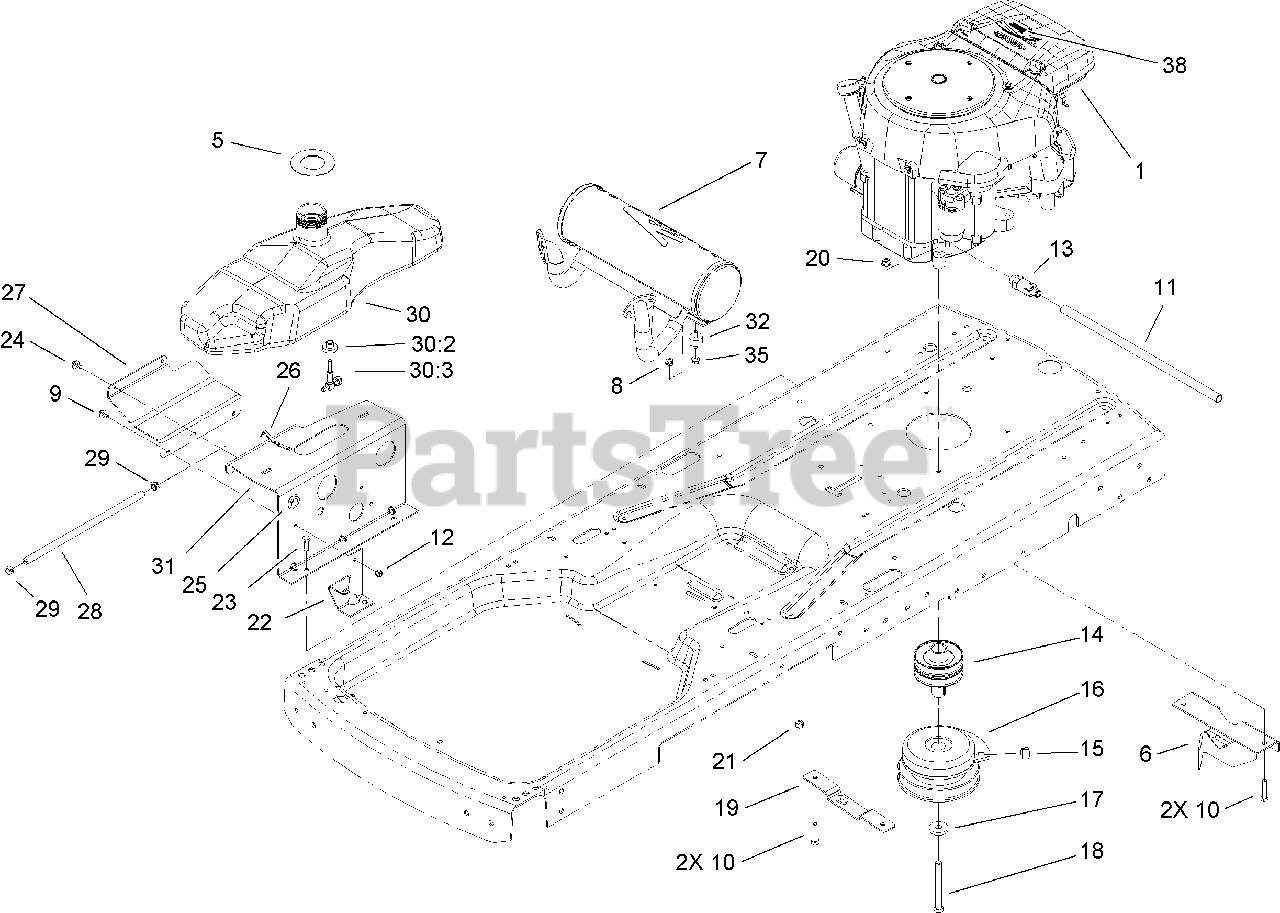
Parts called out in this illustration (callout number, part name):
5	SEAL-FOAM
6	BRACKET-PIVOT
9	SCREW-HWH
10	SCREW-HH
11	TUBE-DRAIN, OIL
12	NUT-LOCK, NI
13	VALVE-DRAIN, OIL
14	PULLEY-ENGINE
16	CLUTCH-PTO, ELECTRIC
18	SCREW-HH
19	PLATE-MOUNT, IDLER
21	NUT-LOCK, NI
22	MOUNT-SPRING
23	SCREW-HH
24	SCREW-HHF
27	PLATE-SUPPORT
28	HOSE-FUEL
30	FUEL TANK ASM
30:3	VALVE-FUEL
32	ISOLATOR-RUBBER
38	DECAL-ENGINE
